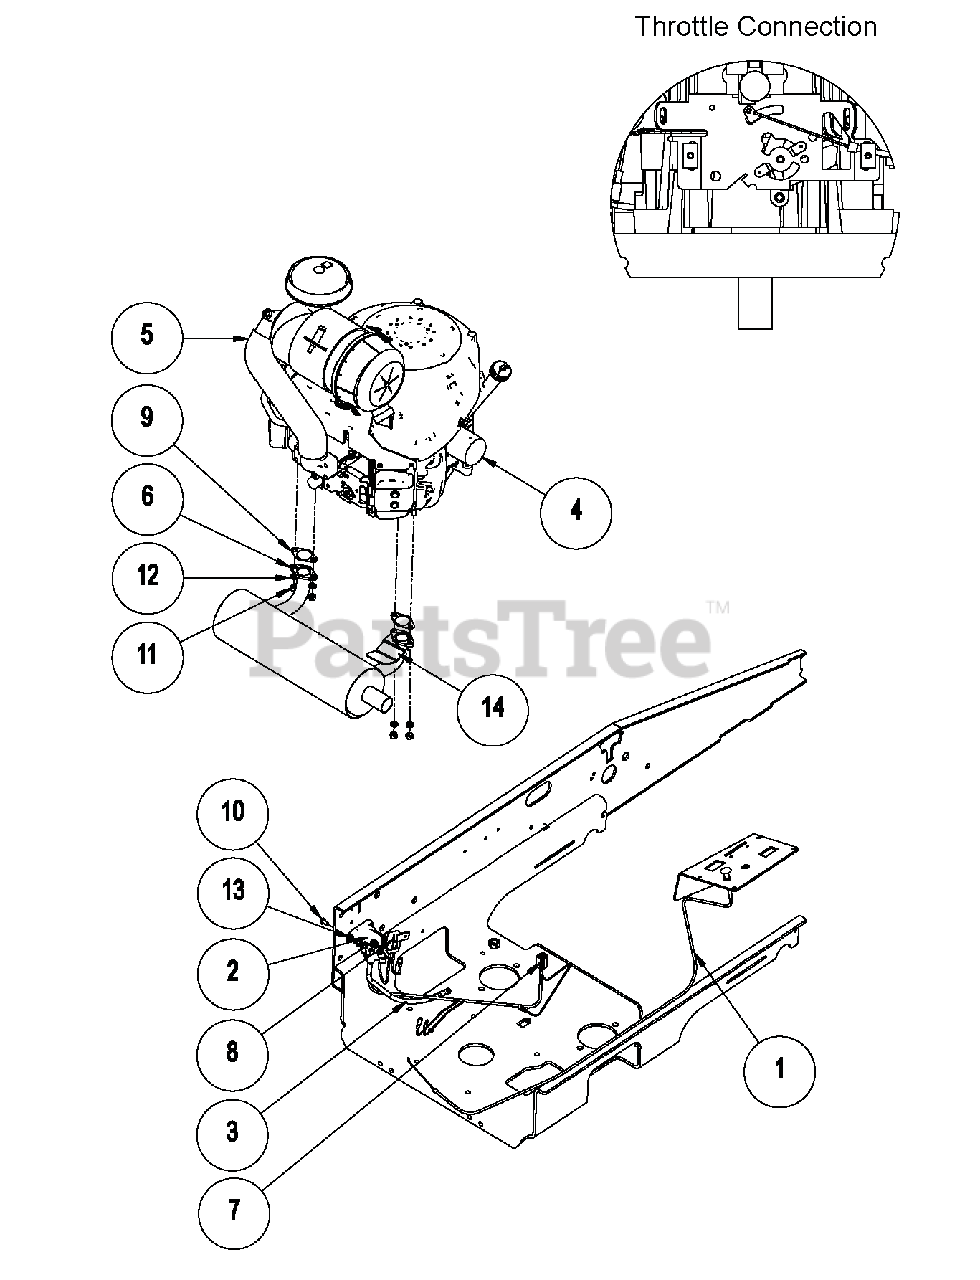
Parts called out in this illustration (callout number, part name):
1	CABLE, CHOKE 48.0"
2	SOLENOID, 12V STARTER
3	CABLE, 12" STARTER
4	OIL FILTER S/O
4	FILTER, PREMIUM BRIGGS OIL S/O
5	ENGINE, KAWASAKI 19HP FH580V
5	ENGINE, KAWASAKI 23HP FH680V
5	ENGINE, 18HP KOHLER ELECTRIC
6	MUFFLER, KAWASAKI FH-HORI
6	MUFFLER, HORI KOHLERCV VRT SFT
7	ADAPTER HARNESS, 19KAI/23KAW
8	ADAPTER HARNESS KAWASAKI, FUSE
8	HARNESS, KOHLER ADAPTER
9	KIT, MUFFLER GASKET S/O
10	BOLT, 1/4-20 X .500 HEX 5
12	WASHER, M8 SPRG LOCK
13	LOCKNUT, 1/4-20 WHIZ Y
14	SHIELD, EXHAUST
